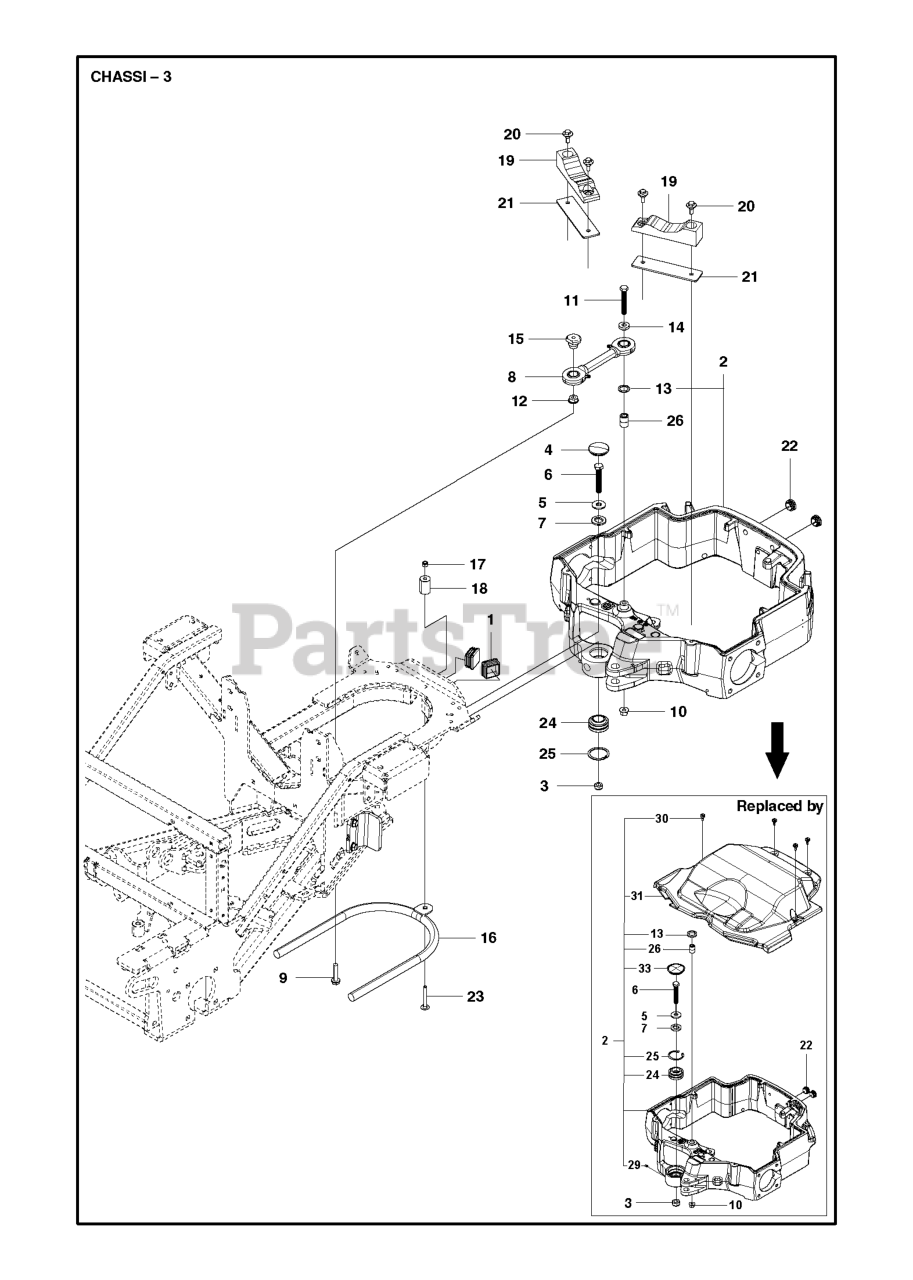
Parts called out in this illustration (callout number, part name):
17	LOCKNUT M8
20	COLLAR SCREW
23	SCREW
29	GREASE NIPPLE
